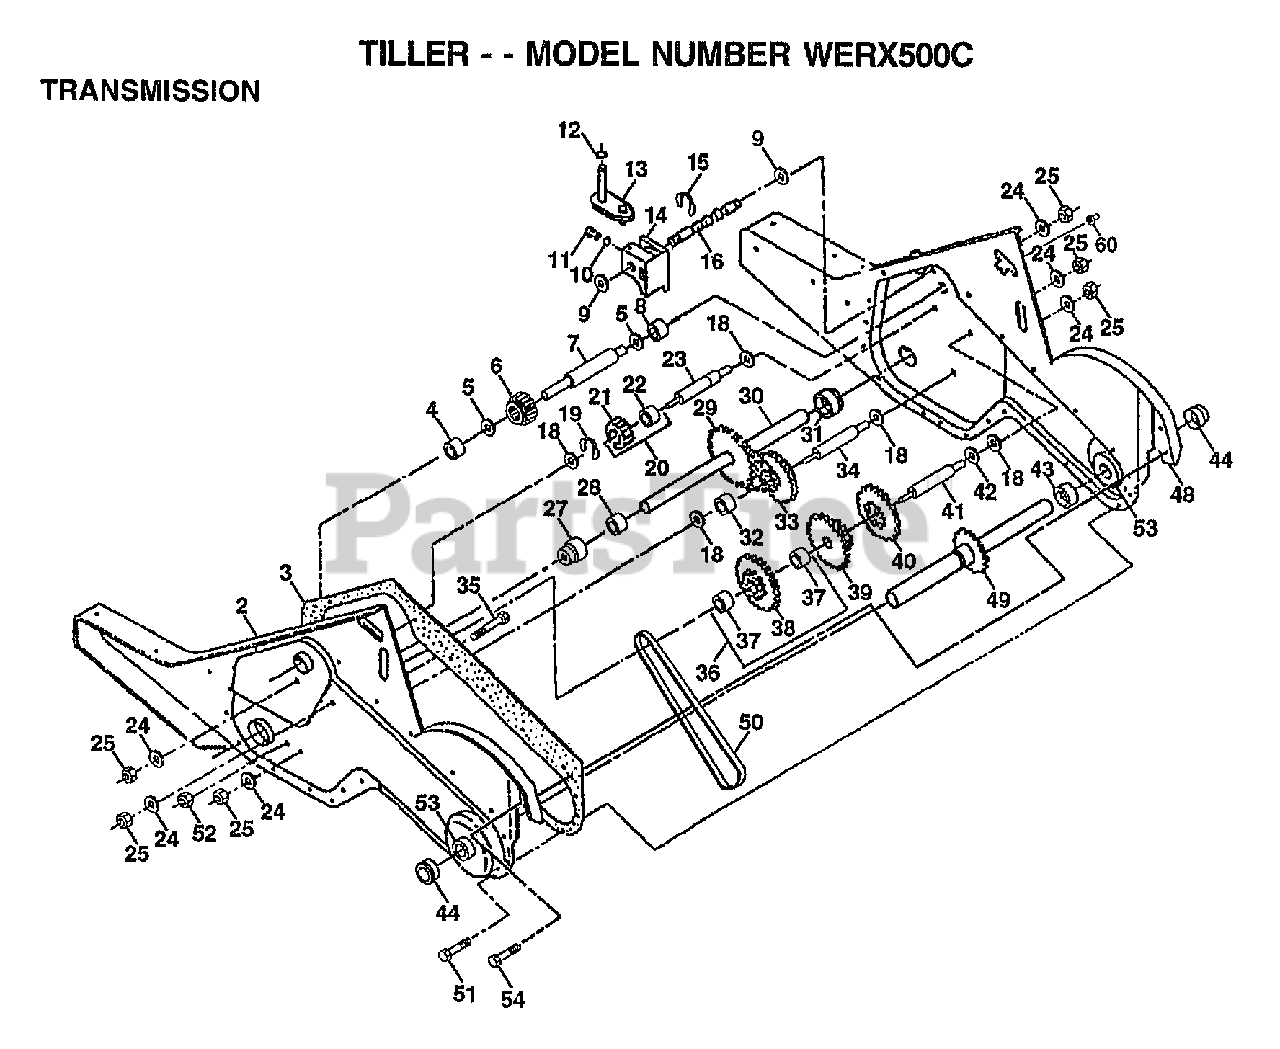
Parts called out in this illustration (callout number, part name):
1	TRANSMISSION ASSY
2	GEARCASE LH W/BEARING
3	GASKET.GEARCASE
4	NEEDLE BRNG LT
5	"T, BEARING"
6	GEAR PINION INPUT
7	"SHAFT.INPUT.""D"""
8	"TI, BEARING"
9	WASHER SEAL
11	SPRING-SHIFT CRT
12	O-RING TI
13	BRACKET ASM SHIFT
14	SHIFT FORK TI
15	KLIP RING
16	SHAFT.SHIFTER
18	WASHER
19	KLIP RING
20	GEAR ASSY CRT
21	GEAR-REV IDLR CRT
22	NEEDLE BEARING TI
23	SHAFT CRT
24	LOCKWASHER
25	NUT.ASF.HEX.7/16
27	BEARING.SHAFT.LH.
28	BUSHING TI
29	CHAIN CRT
30	GROUND SHAFT ASSY
31	BEARING.SHAFT.RH.
32	SPACER TI
33	SPRCKT 8 GEAR CRT
34	SHFT 2ND RED. CRT
35	SCRW WHIZ LOK CRT
36	SPROCKET.ASM.W/BR
37	BEARING
39	GEAR TI
40	GEAR TI
41	REDUCTION SHFT TI
42	BRNG RACE
43	GEARCASE RH W/BEARING
44	SEAL ASM-OIL
48	GEARCASE W/BEARING
49	TINE SHAFT
50	CHAIN.50 LINK TI
51	SCREW
52	NUT.HEX.5/16-18
53	KIT.BEARING
54	SCREW 1/4-20X3/4
60	ZERK M
